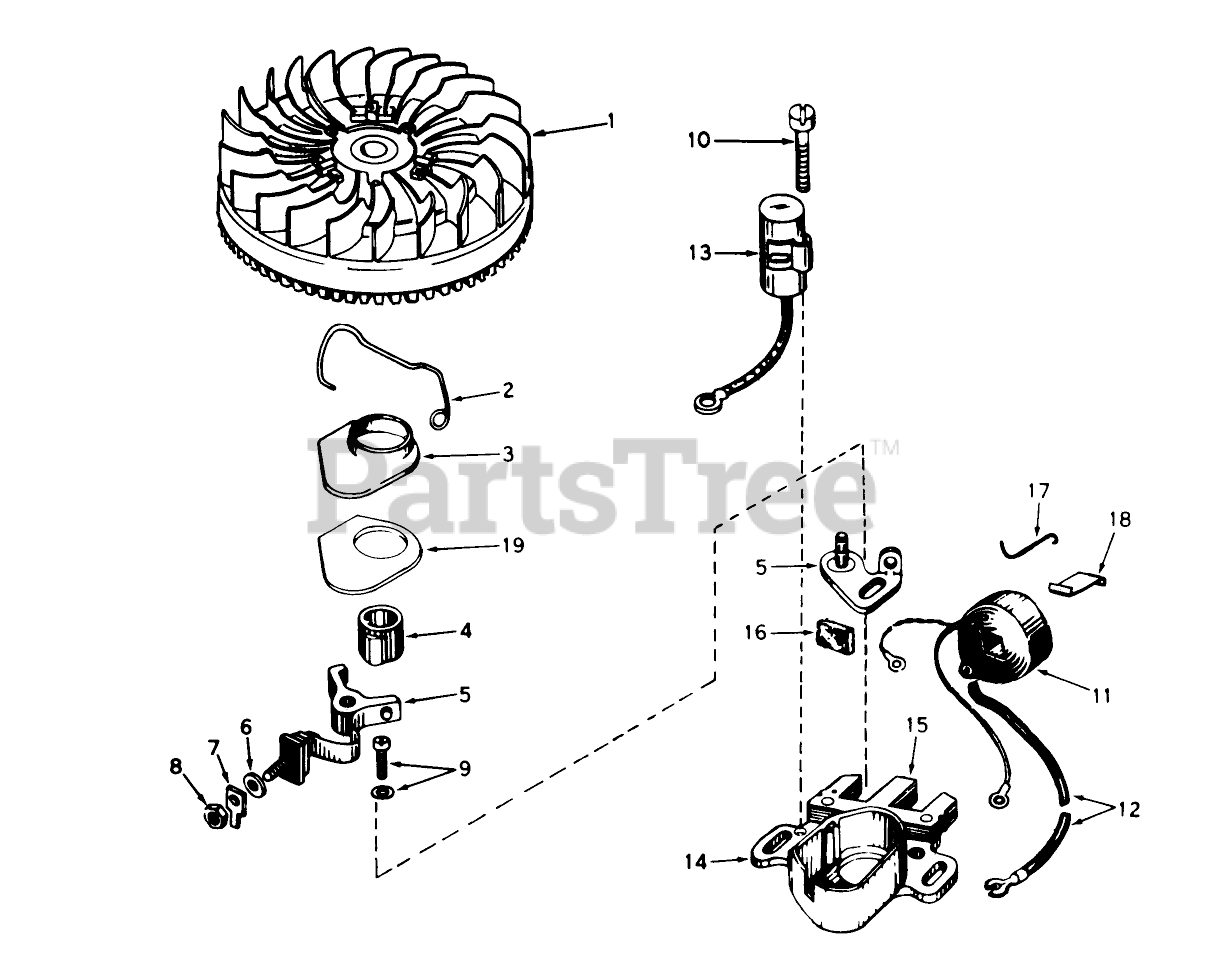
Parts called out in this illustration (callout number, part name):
1	FIywheel
2	Spring Breaker Box
3	Cover, Dust
4	Cam-Breaker
5	Breaker Assy.
6	Washer
7	Terminal, Ground
8	DECAL
9	Breaker Screw
10	Condenser Screw
11	Coil Assy. (Incl. No. 12)
12	Wire, Lead
13	Condenser
14	Core Plate
15	Stator Assy., (Incl. Nos. 2, 3, 5 thru 14 16 thru 19)
16	Felt,Cam Wiper
17	Clip, Coil
18	Spring Coil Wedge
19	Gasket Dust Cover
